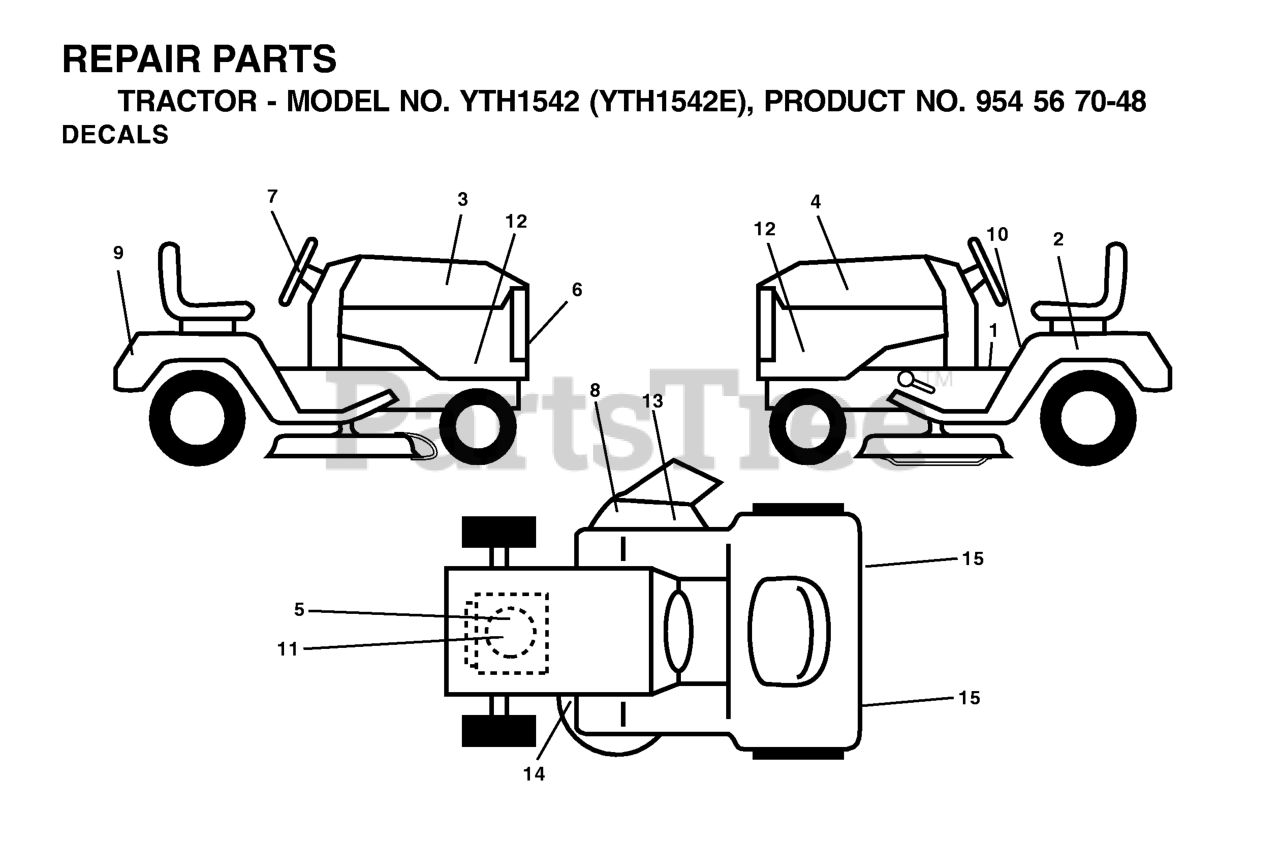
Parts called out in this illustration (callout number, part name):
2	DECAL BTRY SYMBOLS
3	DECAL, HOOD(R)
4	DECAL, HOOD(L)
5	DECAL HP ENGINE
6	DECAL.GRILLE.HUSQ
7	DECAL.WHEEL.STEERING.HUSQ.PERM
8	DECAL.WARN.KEEP.HAND.AWAY
9	DECAL, FENDER
10	DECAL FENDER DANGER
11	DECAL, ENGINE LOGO
13	DECAL DECK "B" 42"
14	DECAL V BELT SCHEMATIC
15	REFLECTOR-TAIL YT
